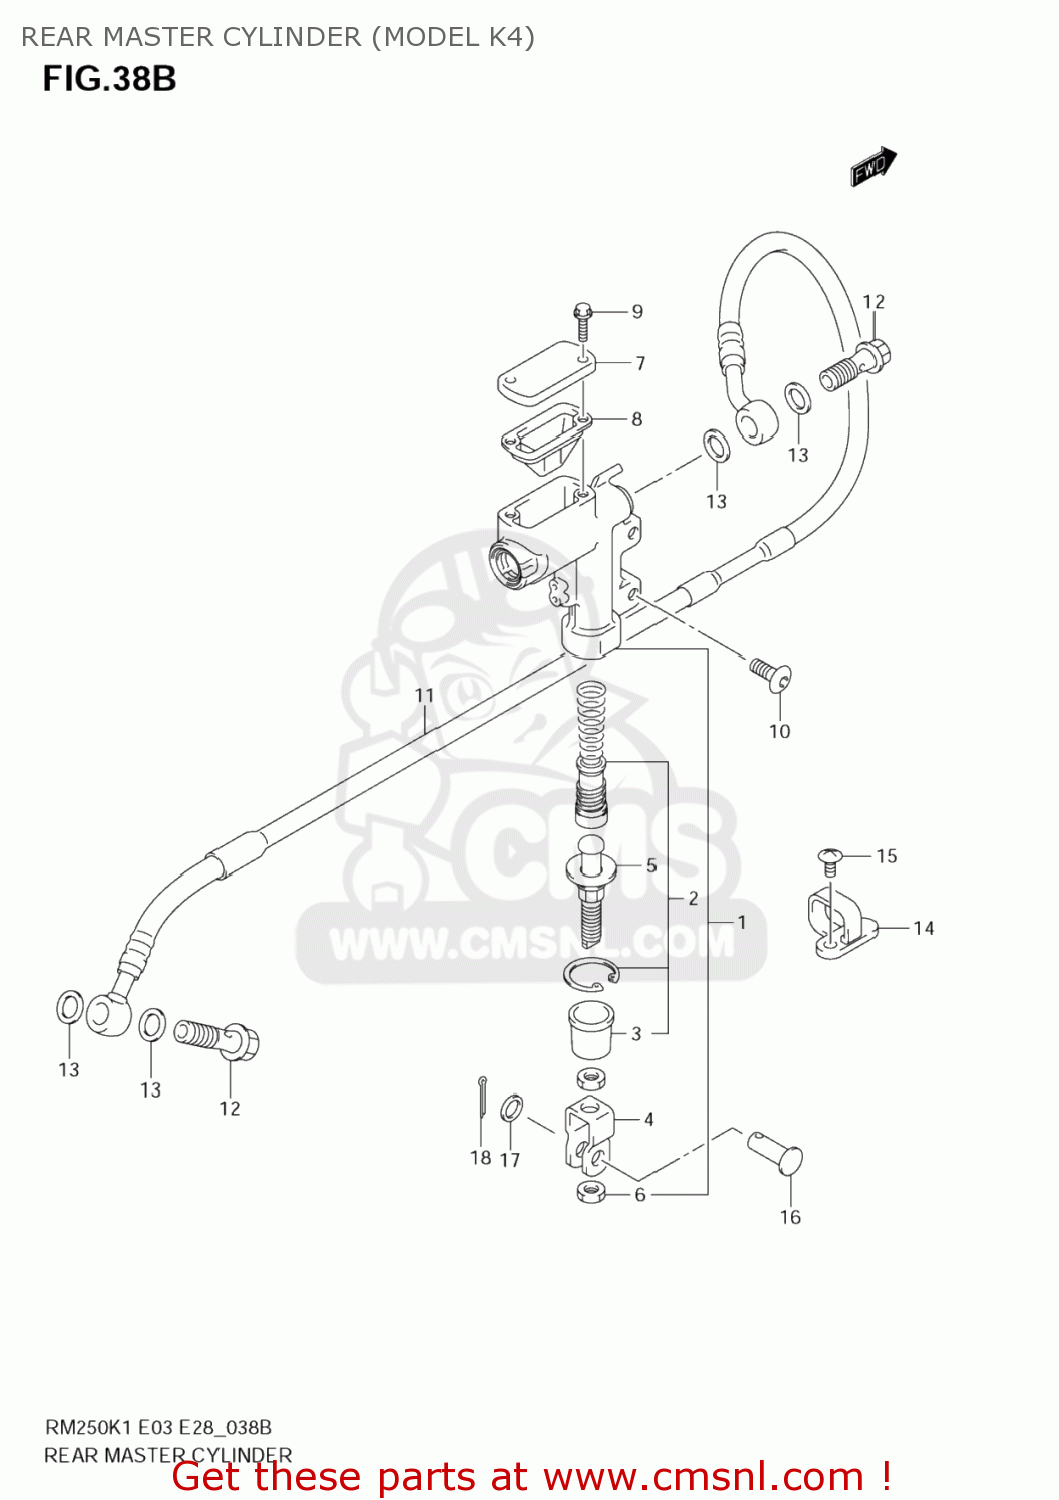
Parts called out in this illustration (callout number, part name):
1	CYLINDER SET,R
2	PISTON/CUP SET
3	BOOT
4	YOKE
5	ROD,PUSH
6	NUT
7	CAP
8	DIAPHRAGM
9	SCREW
10	SCREW(6X16)
11	HOSE, REAR BRAKE
12	BOLT UNION
13	WASHER(10X15X1.5)
14	GUIDE,RR BRAKE
15	SCREW
16	PIN(8X20)
17	WASHER (8.5X14X1.6)
18	PIN
